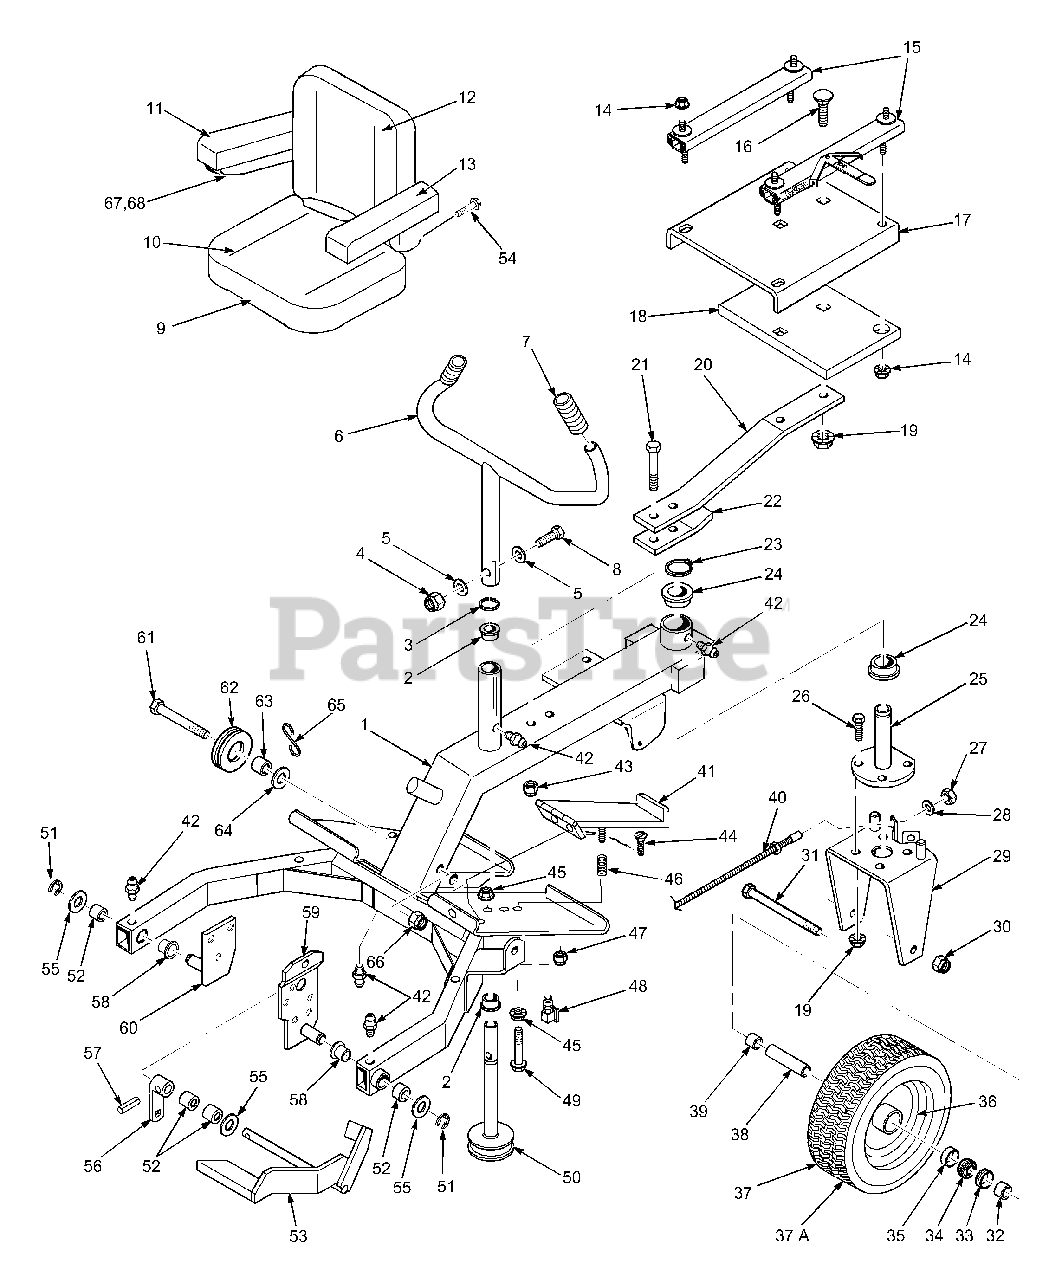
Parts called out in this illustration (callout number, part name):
1	Steering Frame
2	Bronze Bushing, 7/8 ID x 1.0 Flanged
3	Retaining Ring, 7/8 external
4	Hex Nut, Elastic Stop 5/16-18
5	Flat Washer, 5/16 (3/8 x 7/8 x 13 ga.)
6	Steering Handle
7	Grip
8	Bolt, Hex Hd., 5/16-18 x 1-3/4"
9	Seat Assy.
10	Cushion Assembly
11	Arm Pad - R.H.
12	Seat Back Cushion
13	Arm Pad - L.H.
14	Serr. Fl. HH. Nut, 5/16-18
15	Seat Adjuster Track
16	Bolt, RDHD Carr. 3/8-16 x 1-1/2 (52" & 61")
17	Seat Plate
18	Ballast, Seat Mount
19	Serr Fl. Hex Nut, 3/8-16
20	Seat Spring
21	Bolt, Hex Hd., 7-16-14 x 3-1/2"
22	Reinforcement, Seat Spring
23	Retaining Ring, 1-1/8" external
24	Bushing, Oilite - 1-1/8 ID x 1.0 Flanged
25	Rear Wheel Pivot
26	Bolt, Hex Hd., 3/8-16 x 1-1/4"
28	Lock Washer, 3/8 Internal Tooth
29	Rear Wheel Yoke
30	Hex Elastic Stop Nut, 5/8-11
31	Bolt, Hex Hd. 5/8-11 x 9"
32	Spacer, Rear Wheel, short
33	Seal, Grease
34	Bearing Cone
35	Bearing Cup
36	Rim Only
37	Rear Wheel Assy.
37A	Tire Only
38	Sleeve, Rear Wheel
39	Spacer, Rear Wheel
40	Cable, Steering
41	Pedal, Foot Safety Switch
42	Grease Fitting
43	Hex Elastic Stop Nut, 7/16-14
44	Screw, Phillips flat hd #10-32 x 3/4"
45	Serr. Fl. Hex Nut, 1/4-20
46	Spring, Foot Safety Switch
47	Hex Nut, Elastic Stop Lock, 1/4-20
48	Switch, Foot Safety
49	Bolt, Hex Hd., 1/4-20 x 1-3/4"
50	Steering Shaft
51	Retaining Ring 3/4 Ext. "E"
52	Bushing, oillube - 3/4 ID x 1.0
53	Foot Pedal
54	Screw w/washer, 1/4-20 x .75"
55	Flat Washer, 3/4 x 1-1/4 x 16 Ga.
56	Foot Pedal Arm
57	Pin, Drive Lock 3/16 x 1-1/4"
58	Bushing, oillube - 3/4 x .50 Flanged
59	Sulky Mtg. Brkt. L.H.
60	Sulky Mtg. Brkt. R.H.
61	Bolt, Hex Hd., 1/2-13 x 5-1/2"
62	Pulley, Winch Cable
63	Bushing, oillube - 1/2 ID x .56
64	Flat Washer, 1/2 (.562 x 1.375 x .109)
65	Retainer, Winch Cable
66	Hex Elastic Stop Nut, 1/2-13
67	Arm Rest Bracket, Left Hand
68	Arm Rest Bracket, Right Hand
